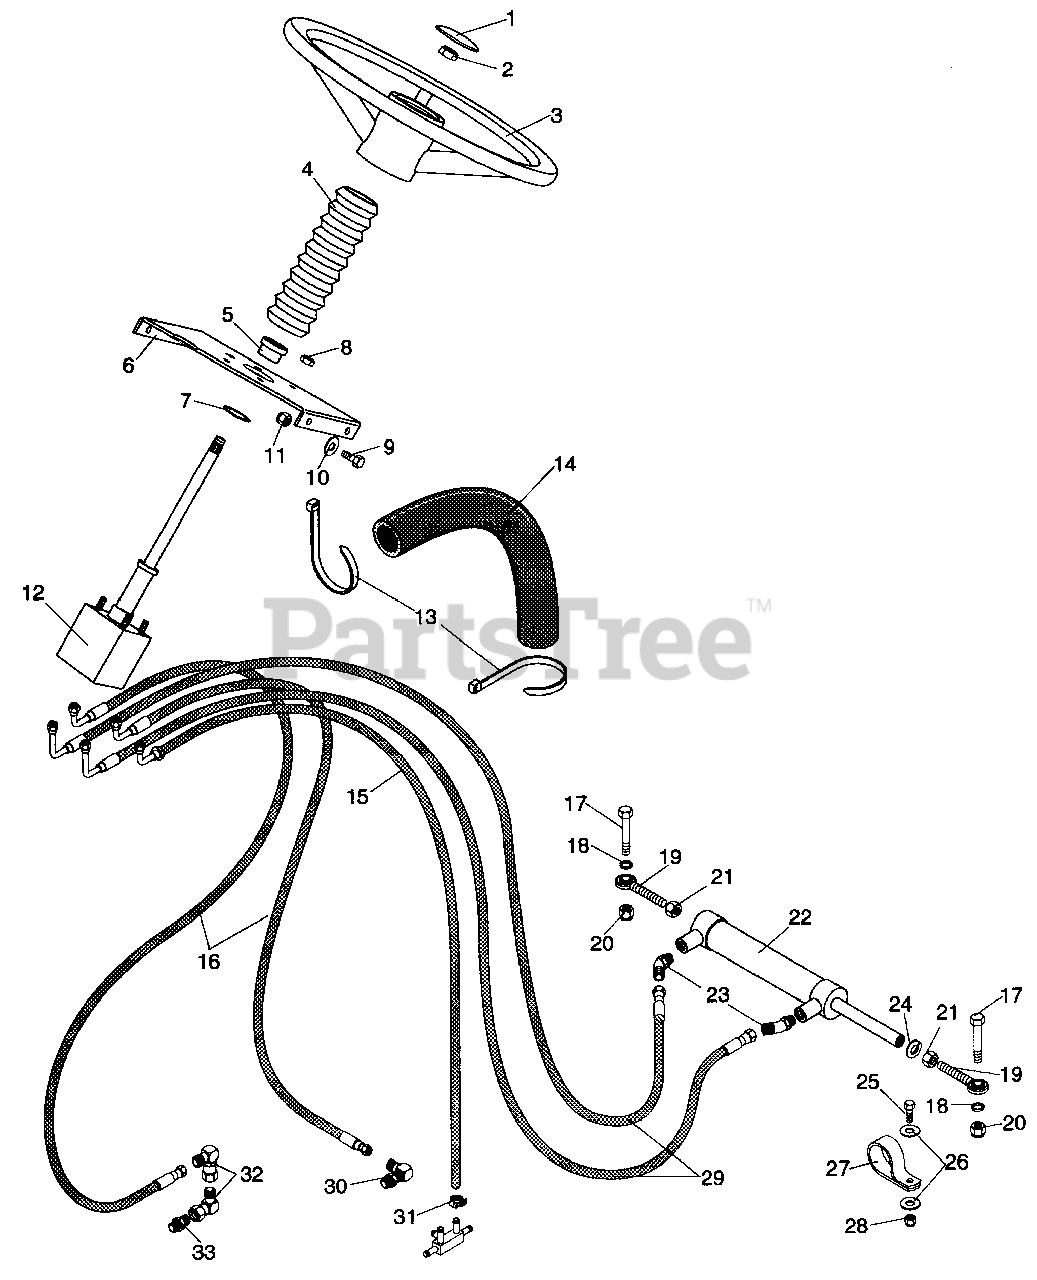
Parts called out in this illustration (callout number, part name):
1	STEERING WHEEL CAP
2	NUT JAM .625 - 11 PL
3	G-STEERING WHEEL
4	STEERING COLUMN BOOT
5	BSHG-FLG .762 X 1.0 X .580 X 1.48 NY
6	BRKT-STEERING PUMP
7	RG-RET-EXT 1.31 X .05
8	NUT-LK .312-24 W/INSR
9	BLT-HEX .31-18 X .75 PL GR 5
10	WSHR-FL-STL .344 X .688 X .065
11	NUT-LK-NYL .312-18 PL
12	PWR STRG UNIT
13	TIE WRAP, BLACK
14	SLEEVE 12
15	ASM, HYDRAULIC HOSE
16	ASM, HYDRAULIC HOSE
17	BLT-HEX .50-13 X 2.00 PL GR 5
18	BUSH., S .520 X .625 X .125 ST
19	ASM, ROD END(R.H.)
20	NUT-LK-NYL .50-13 PL
21	NUT-JAM .50-20 PL
22	CYL, STEERING
23	ADPT, P-H #3503-6-6
24	WSHR-LOCK .50 REG.
25	BLT-HEX .38-16 X 1.00 PL GR 5
26	WSHR-FL-STL .406 X .812 X .065 PL
27	CLAMP, NYLON
28	NUT-LK-NYL .375 - 16 PL
29	ASM, HYDRAULIC HOSE
30	ADPT 2503-6-6
31	HOSE CLAMP
32	GSKT, ADAPTOR
33	ADPT-PIPE .56-18 O RING TO .5
NS	REPAIR KIT, ROSS POWER STEERING
NS	DECAL, STEERING WHEEL CAP
